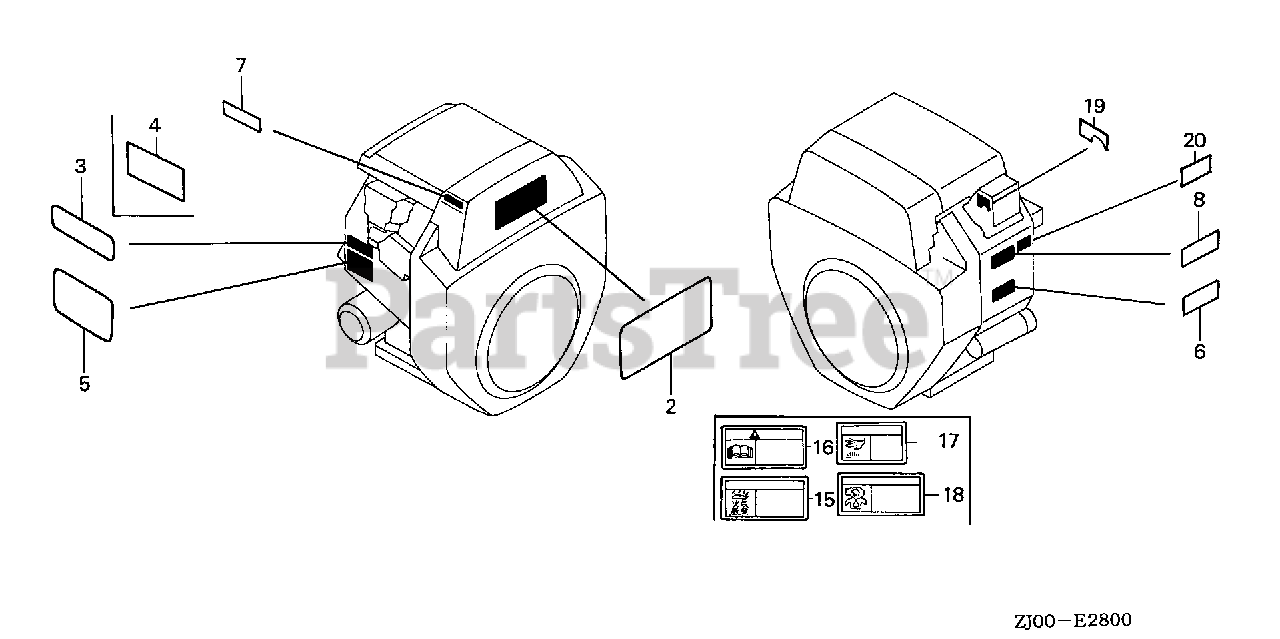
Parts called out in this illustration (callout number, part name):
3	LABEL, SPECIFICATION (GX610)
5	LABEL, CAUTION
16	MARK, CAUTION (JAPANESE)
17	MARK, HEAT CAUTION
